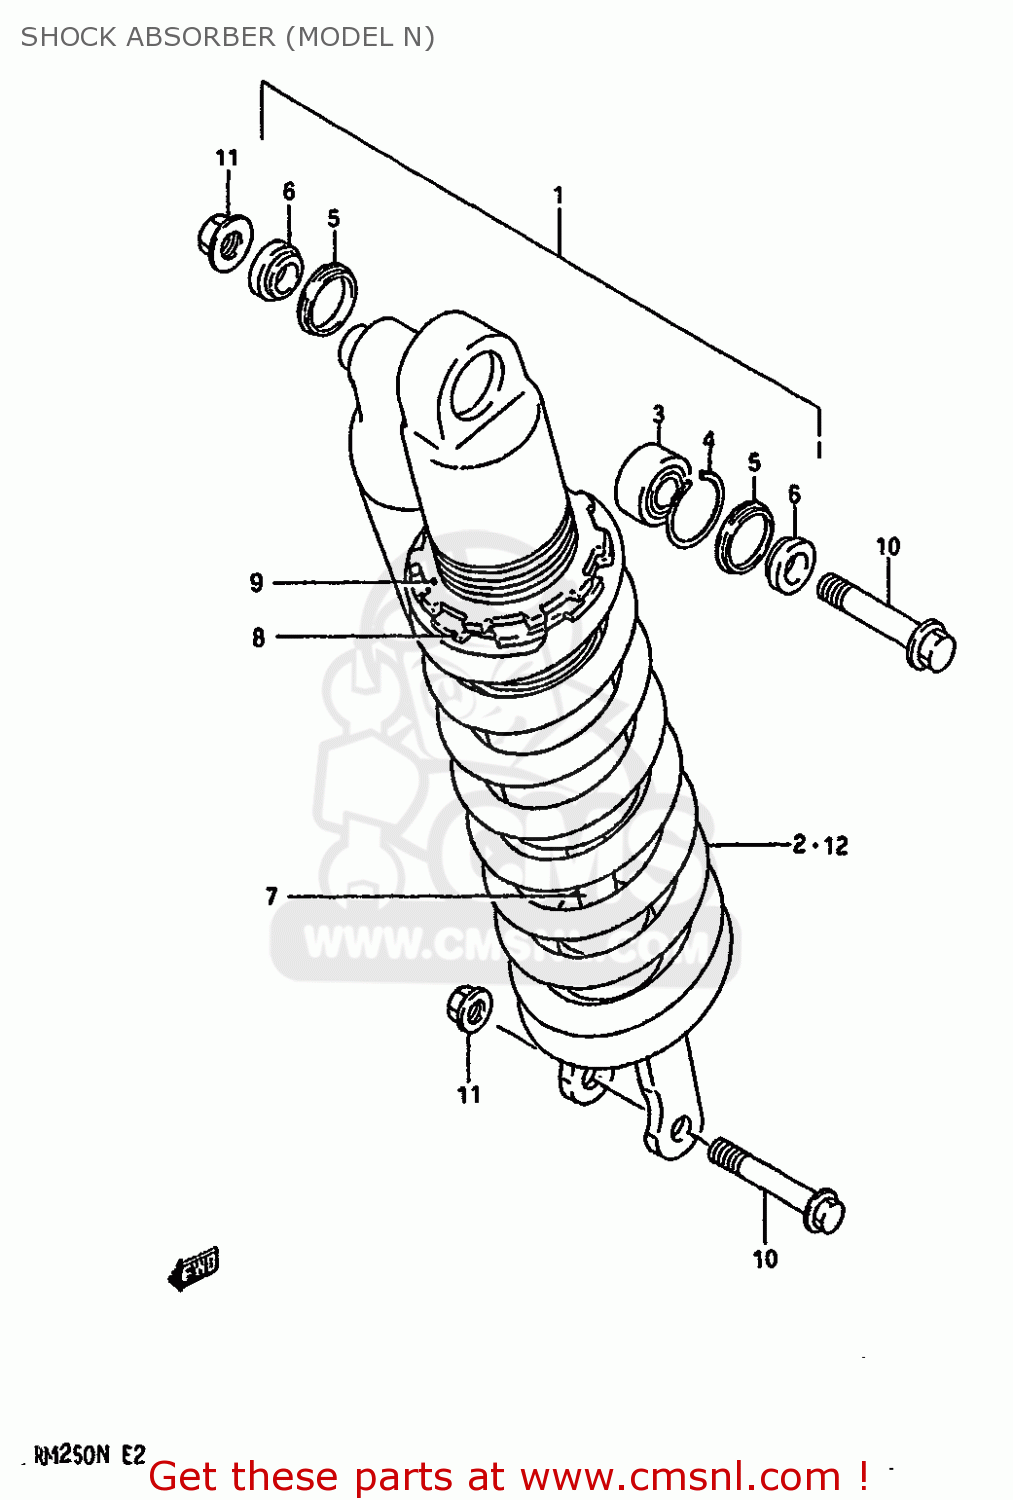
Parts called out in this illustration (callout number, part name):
1	ABSORBER ASSEMBLY,REAR SHOCK
2	SPRING
3	BEARING,REAR SHOCK ABSORBER
4	RING,STOPPER
5	SEAL,DUST
6	COLLAR
7	ROD,PISTON
8	GUIDE,SPRING
9	NUT
10	BOLT,REAR SHOCK ABSORBER
11	NUT
12	SPRING,REAR (K=5.4)
